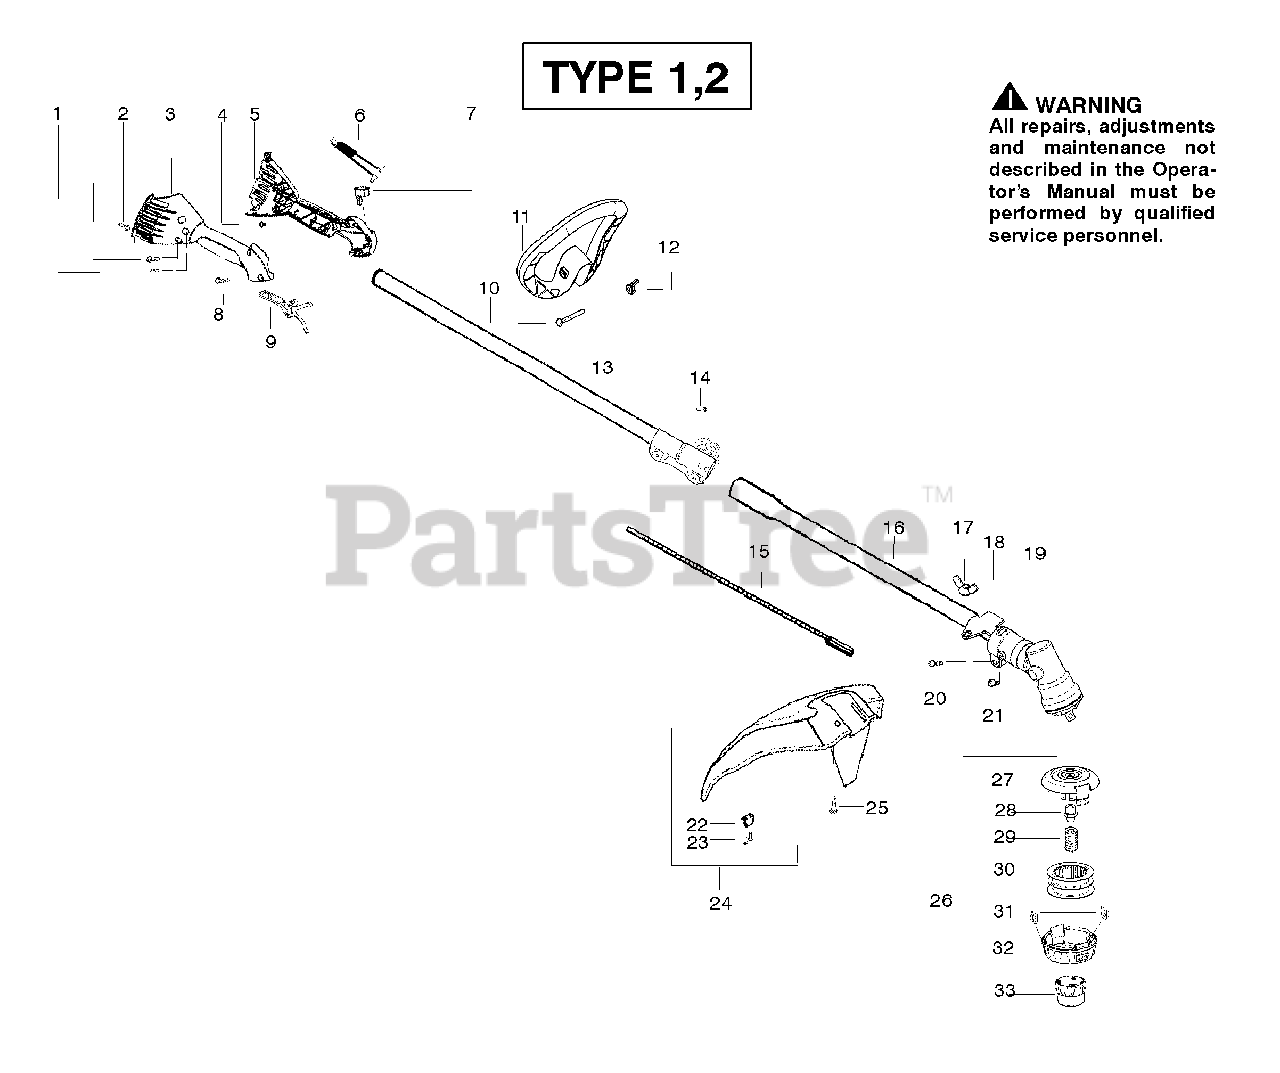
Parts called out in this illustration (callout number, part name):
1	Screw-alignment
3	Hsg.-Throttle right
4	Screw-Cable Retention
5	Hsg.-Left throttle
6	Assy-Wire
7	Kit-Switch
9	Lever-Throttle
11	Assy-Handle
12	Wingnut
13	Kit-Upper Shaft
15	Shaft-Flex
16	Kit-Lower Shaft
17	Wingnut
18	Bracket-Shield
22	Limiter-Line
24	Kit-Shield Assy.
26	Assy-TNG VII
30	Accy-Wound Spool
31	Eyelet
32	Cover
